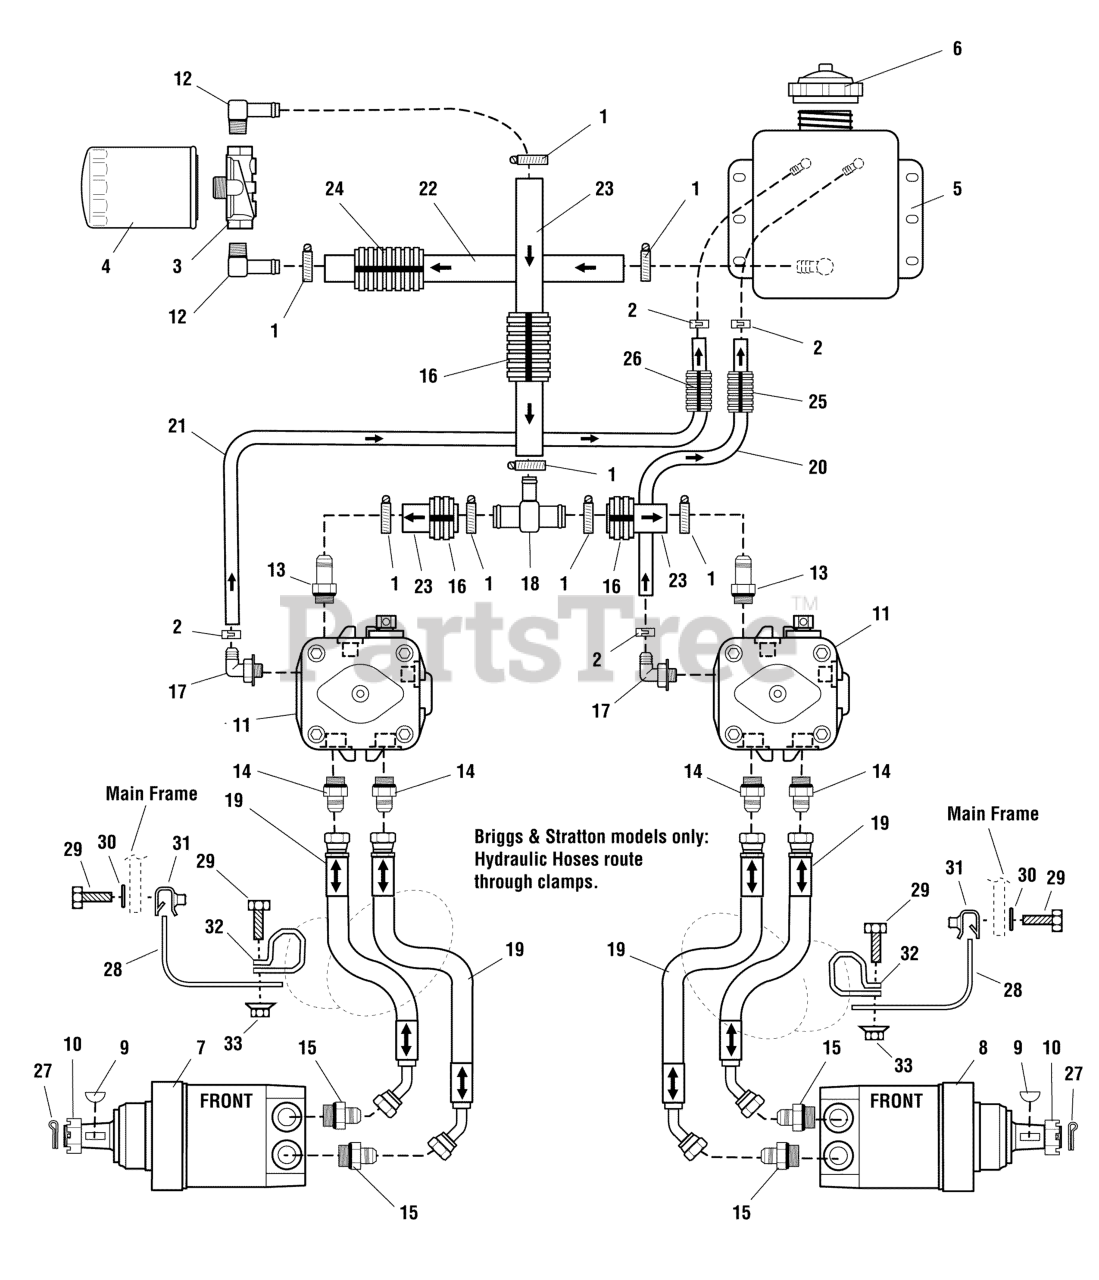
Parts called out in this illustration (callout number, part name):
1	CLAMP, #10 HOSE, STAINLESS
2	CLAMP, Hose
3	FILTER HEAD
4	FILTER, HYDRAULIC, SERVICE PART (PKG)
5	KIT, TANK HYDRAULIC, 3QT W/ FITTINGS
6	CAP, HYDRAULIC RESERVOIR
7	HYDRAULIC WHEEL MOTOR-LEFT, Complete
8	HYDRAULIC WHEEL MOTOR-RIGHT, Complete
9	KEY, WOODRUFF, #1008, 5/16 X 1
10	NUT, CASTLE, 1-20
12	FITTING, 1/2NPT-5/8" HOSE, 90 DEG
13	FITTING, STRAIGHT, HYD #12618
14	FITTING, #8 O-RING X #8 JIC, STR
15	FITTING, #10 O-RING X #8 JIC, STR
16	LOOM, CONVOLUTED SPLIT, 1" ID - 8" LONG
17	ADAPTER, 90 DEG. 9/16 - 3/8 BARB
18	TEE, HYDRAULIC, BEADED HOSE, 5/8 X 5/8 X 5/8
19	HOSE ASSEMBLY, (33)
20	HOSE, 3/8" PUSH-LOCK, 12.00"
21	HOSE, 3/8" PUSH-LOCK, 17.50"
22	HOSE, 5/8" PUSH-LOCK, 11.50"
23	HOSE, 5/8" PUSH-LOCK, 10.00"
24	LOOM, CONVOLUTED SPLIT, 1 ID - 9.5 LONG
25	WIRE LOOM, 5/8" ID. 10" LONG
26	WIRE LOOM, 5/8" ID. 15" LONG
27	PIN, COTTER, 1/8 X 2" (SV)
28	PLATE, HOSE ANCHOR - RED
29	BOLT, 5/16-18 X 1" GRD5 YZ
30	WASHER, 5/16" SAE
31	BODY CLIP, 5/16-18-7GA MATERIAL
32	CLAMP, VINYL INSULATED, 1.75
33	NUT, 5/16-18 HEX SERRATED FLANGE (SMALL)
